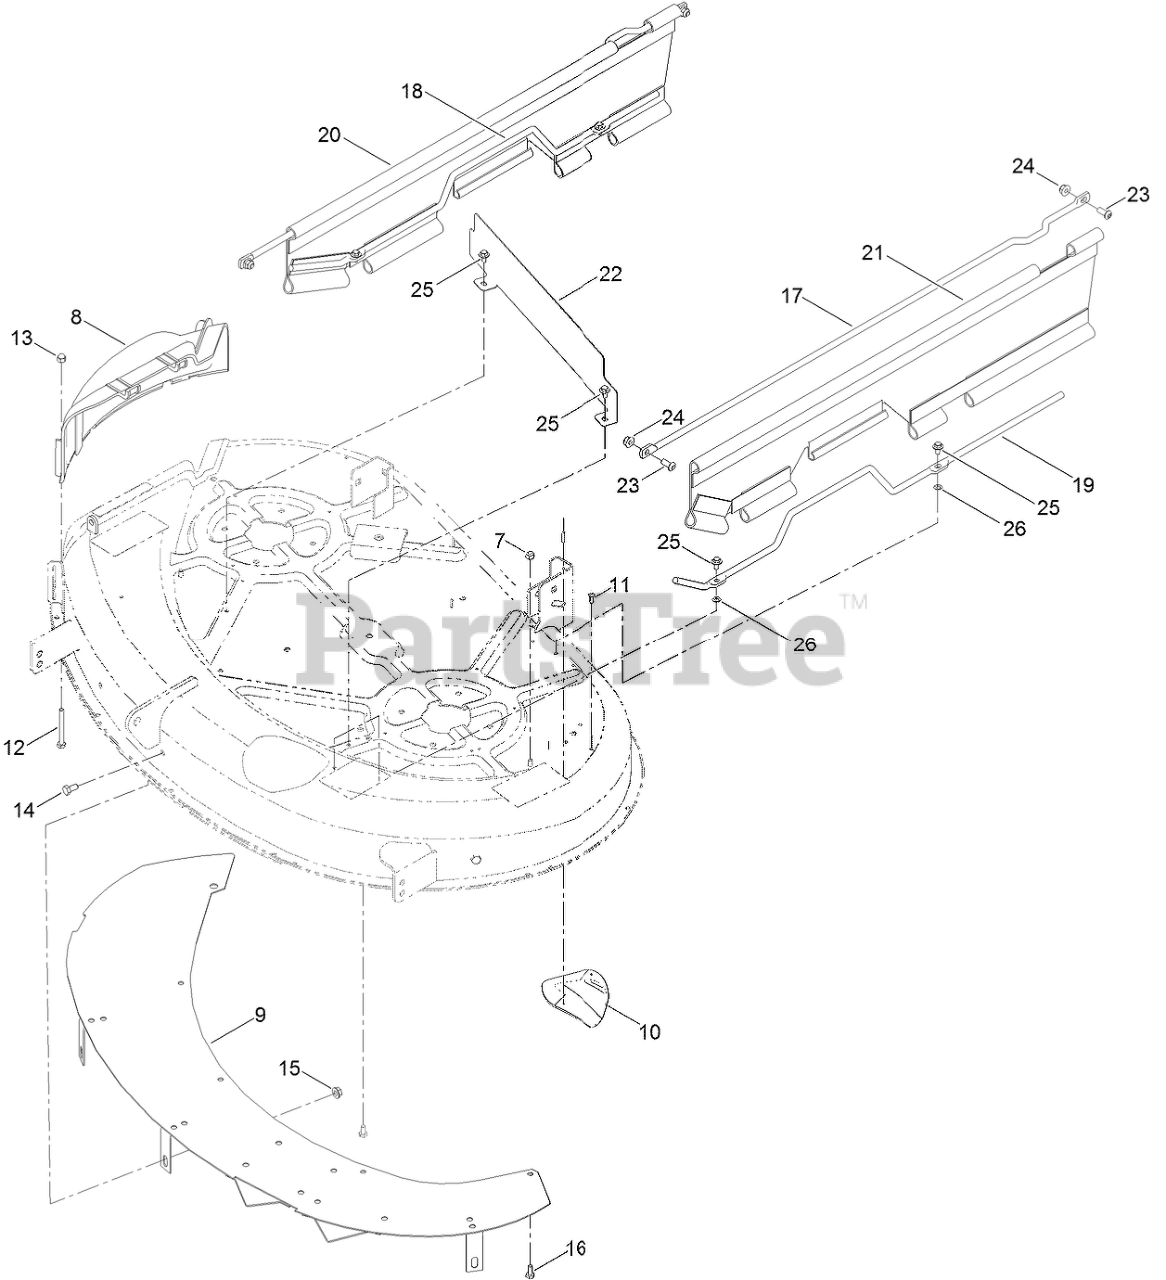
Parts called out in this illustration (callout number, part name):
7	NUT-LOCK, NI
8	COVER-DISCHARGE
9	BAFFLE UPPER ASM
10	PLATE-KICKER
11	SCREW-PPH
12	SCREW-HH
13	NUT-CAP
14	SCREW-HH
15	NUT-HF
16	SCREW-HH
17	ROD-SUPPORT, UPPER
18	ROD-SUPPORT, LOWER (RH)
19	ROD-SUPPORT, LOWER (LH)
20	RH GUARD SIDE
21	GUARD-SIDE, LH
22	SHIELD-FRONT, DECK
23	SCREW-HSBH
24	NUT-HF, NI
25	SCREW-HHFTF
26	NUT-RETAINING
